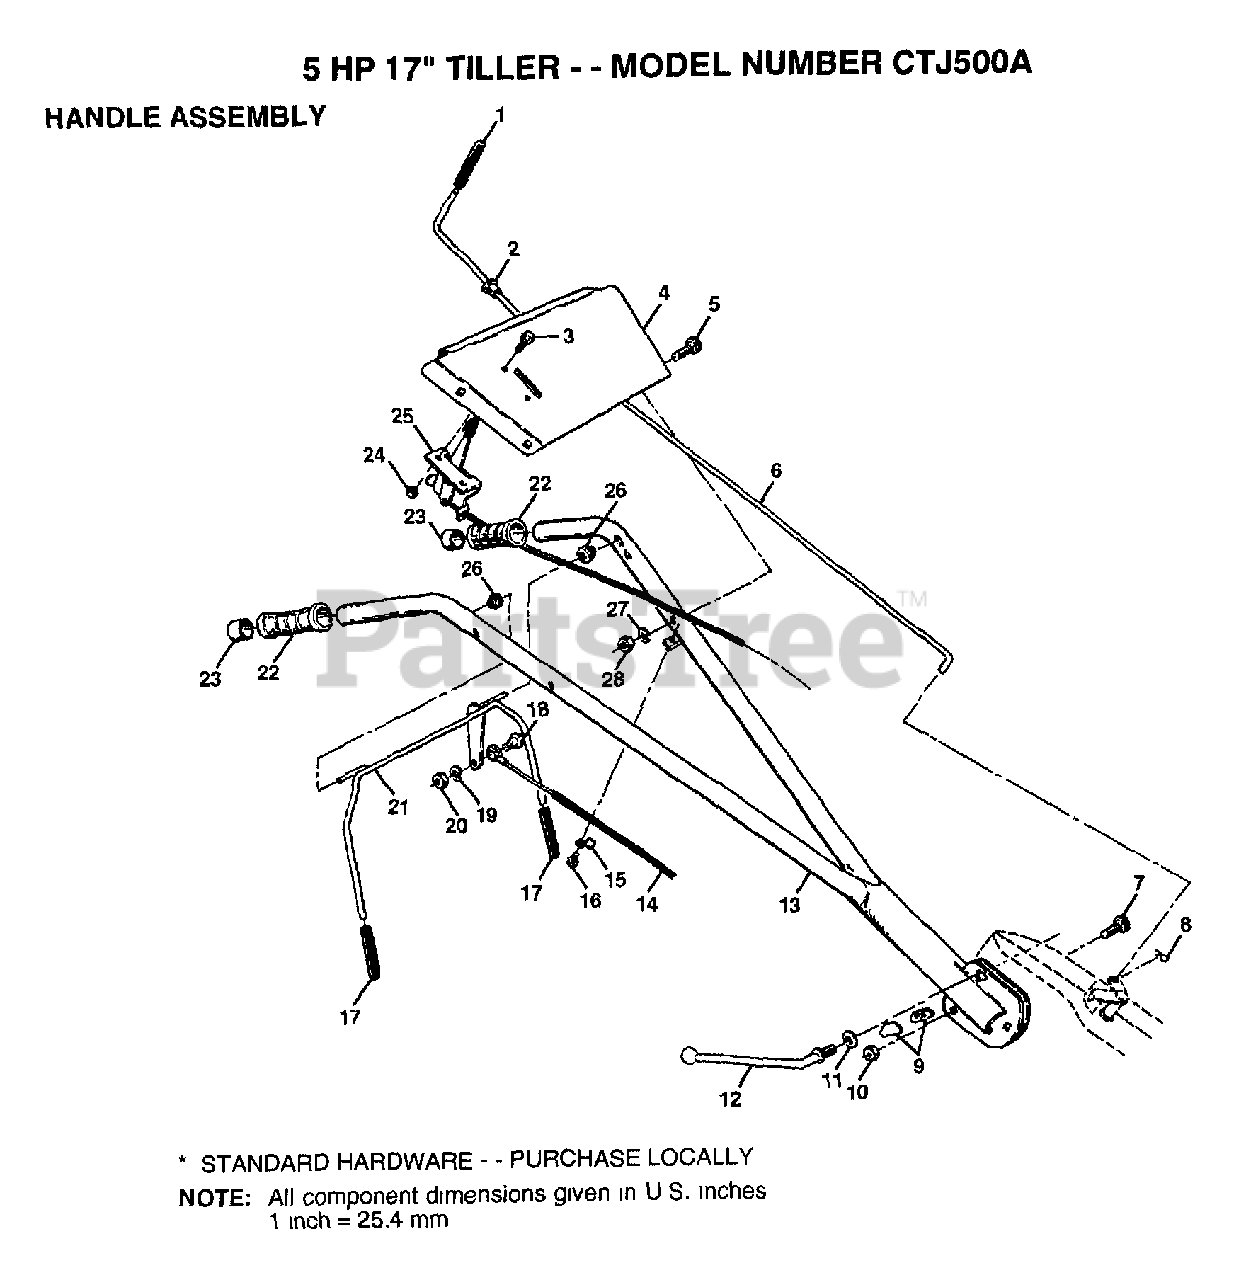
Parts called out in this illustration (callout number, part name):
1	GRIP TI
2	BUSHING
3	SCREW
5	BOLT CARRIAGE CRT
6	ROD SHIFT CRT
7	BOLT D
8	RETAINER M
9	LOCK CRT
10	LOCKNUT
11	WASHER CRT
12	LEVER LOCK CRT
14	CABLE.CLUTCH.CRT
15	CONDIUT CLIP T
17	GRIP BAR CRT
18	SHOULDER BOLT ST
19	LOCKWASHER
21	HANDLE BAR CRT
23	CAP CRT
25	"CONT,THROTTLE"
27	LOCKWASHER
